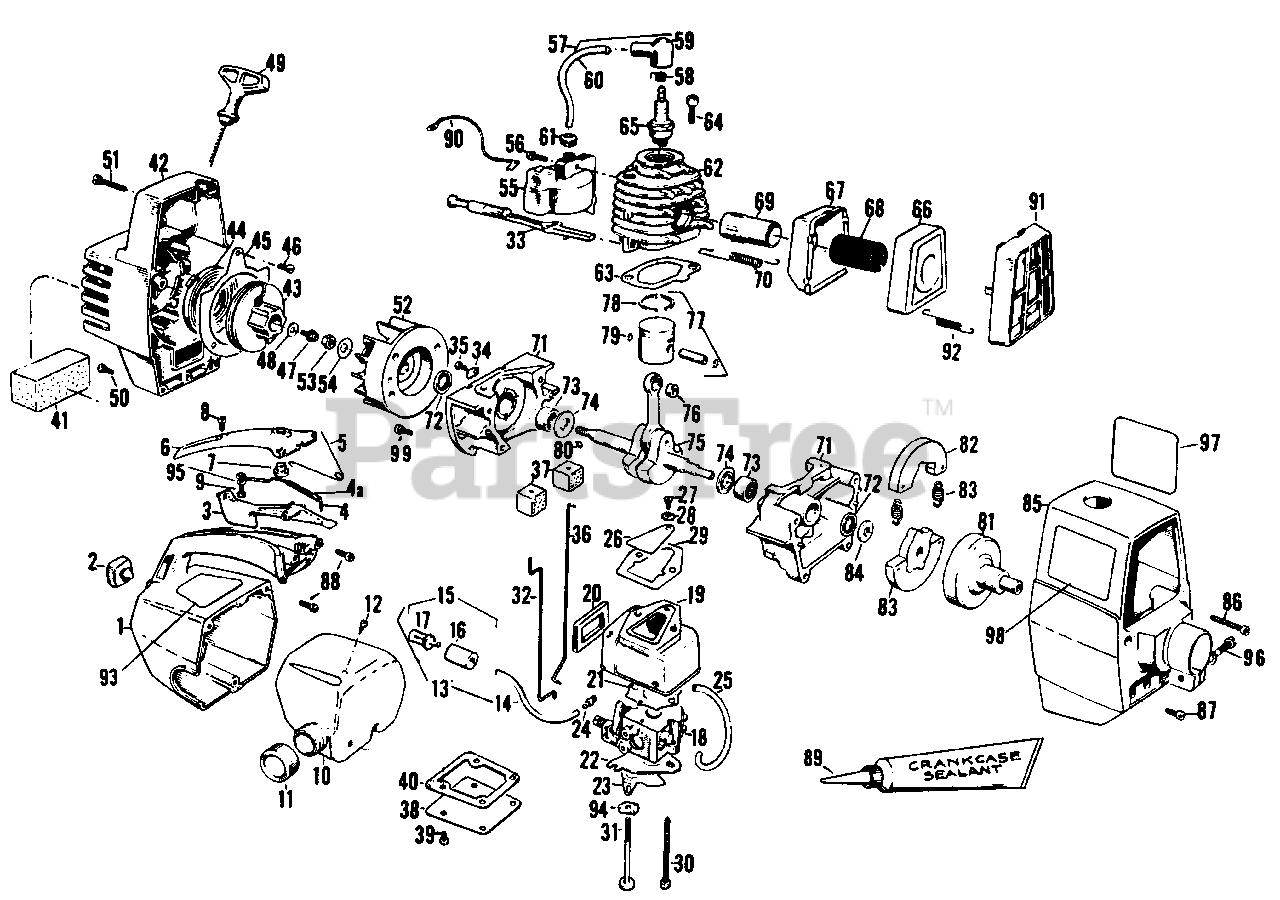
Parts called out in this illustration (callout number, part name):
1	Handle & Fuel Tank Housing
1	"O" Ring-Shoulder Harness
2	Bumper-Fuel Tank Housing
3	Trigger-Throttle
4	Spring-Stop Switch
5	Trigger Spring
6	Handle Cover
7	Button-Stop Switch
8	Screw-Handle Cover
9	Screw-Stop Switch Spring
10	Fuel Tank
11	Fuel Cap
12	Duck Bill Valve
13	Fuel Line Assy
14	Fuel Line
15	Fuel Pickup Assy
16	Fuel Filter
17	Fuel Filter Weight
18	Carburetor
19	Carburetor Housing
20	Seal Carburetor Case
21	Carburetor Gasket
22	Choke Wire Guide Plate
23	Choke Shutter
24	Fuel Line Fitting
25	Fuel Line Carburetor
26	Reed Valve
27	Screw-Reed Valve
28	Washer-Reed Valve Screw
29	Gasket-Carburetor Case to C'case
30	Screw Carburetor
31	Screw-Carburetor Shoulder
32	Choke Wire
33	Choke Knob
34	Clamp-Choke Wire
35	Screw-Choke Rod Clamp
36	Throttle Wire
37	Throttle-Choke Wire Boots
38	Cover-Carburetor Case
39	Screw-Carburetor Case Cover
40	Gasket-Carburetor Case Cover
41	Air Filter
42	Fan Housing
43	Starter Pulley
44	Starter Recoil Spring
45	Air Baffle
46	Screw Air Baffle
47	Screw-Starter Pulley
48	Washer-Starter Pulley
49	Rope and Handle-Starter
50	Screw-Fan Housing Bottom
51	Screw-Fan Housing Top
52	Flywheel Assy
53	Nut-Flywheel
54	Washer-Flywheel
55	Module-Ignition
56	Screw-Ignition Module
57	High Tension Lead Assy
58	Connector-Spark Plug Lead
59	Boot-Spark Plug
60	High Tension Lead Wire
61	Grommet-Plug Wire
62	Cylinder
63	Gasket-Cylinder
64	Screw-Cylinder
65	Spark Plug (Champion RC-J8)
66	Cover Muffler
67	Body Muffler
68	Screen-Spark Arresting
69	Diffuser-Muffler
70	Spring-Muffler Attachment
71	Crankcase Assy
72	Seal-Crankshaft
73	Bearing-Crankshaft
74	Washer-Crankshaft Thrust
75	Crankshaft & Rod Assy
76	Bearing-Wrist Pin
77	Piston Assy
78	Piston Ring
79	Retainer-Wrist Pin
80	Key-Flywheel
81	Drum-Clutch and Drive Adaptor
82	Clutch Assembly
83	Spring-Clutch
84	Washer-Inner
86	Screw-Shroud Top
87	Screw-Shroud Bottom
88	Screw-Fan Housing to Handle & Fuel Tank
89	Sealant-Crankcase (not supplied)
90	Wire-Switch Lead
91	Guard-Muffler
92	Spring-Muffler Guard
93	Decal-Starting Instruction
94	Washer-Wave
95	Washer-Stop Switch Spring
96	Bolt-Pinch Clamp
99	Screw-Crankcase
